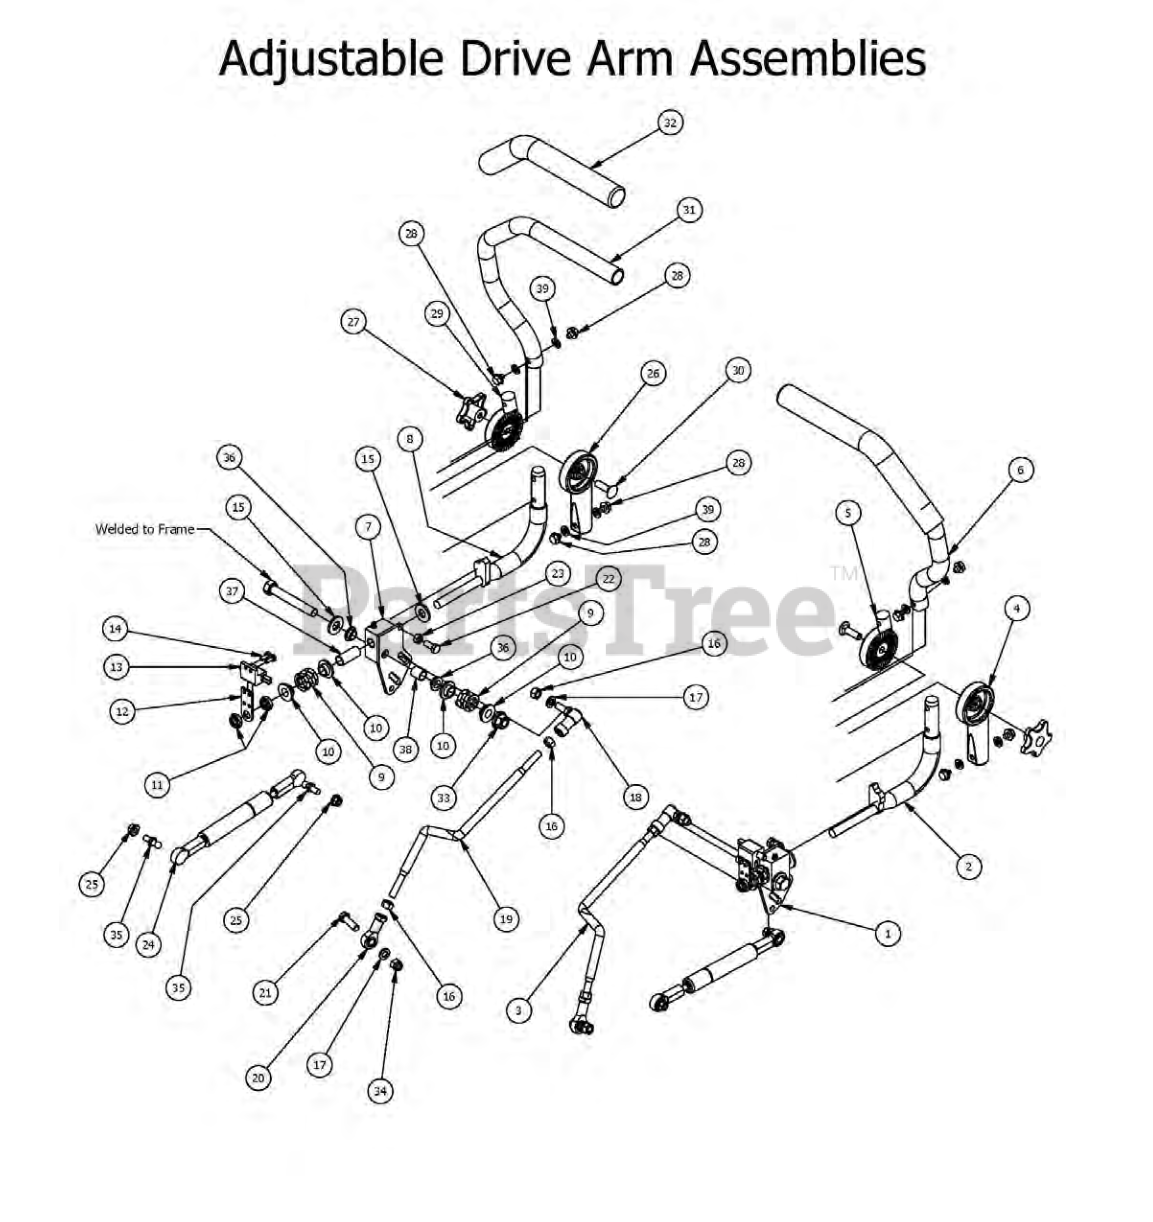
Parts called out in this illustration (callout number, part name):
1	2013 Drive Lever Housing (Right)
2	Steering Arm Elbow-Right
3	Push Rod Right
4	Lower Adjuster-Steering Arm- Right
5	Upper Adjust Steering Arm- Right
6	Upper Tube-Adjustable Steering
7	2013 Drive Lever Housing (Left)
8	Steering Arm Elbow - Left
9	Drive Lever Spring
10	515 ID Nylon Shoulder Washer
11	1/2" Nylcock Nut (1/2 Jam)
12	MZ Switch Bracket
13	Safety Switch
14	12-24x 1/2 HWH Bolt
15	505 Nylon Spacer
16	3/8" Fine Threaded Jam Nut
17	3/8" Lock Washer
18	3/8-24 Quick Release Ball Joint
19	Push Rod Left
20	Spherical Rod End - Outlaw
21	3/8" x 1 1/4" Hex Bolt
22	5/16" x 3/4" Hex Bolt
24	Steering Damper
25	5/16" Flange Nut
26	Lower Adjuster-Steering Arm- Left
27	Black Knob for Adjustable Steering Arm
28	5/16-18 1/2 HWH Bolt-Steering
29	Upper Adjuster-Steering Arm-Left
30	3/8" 1 1/4" Carriage Bolt
31	Upper Tube-Adjustable Steering
32	Black Steering Grip
33	1/2-13 Mechanical Lock Nut Grade F
34	3/8 Nylock Nut
35	10mm Damper Ball Stud-Steering
36	1/2" Oil Impregnated Bushing
37	Drive Arm Block Insert-long
38	Drive Arm Block Insert-short
39	5/16" Lock Washer
